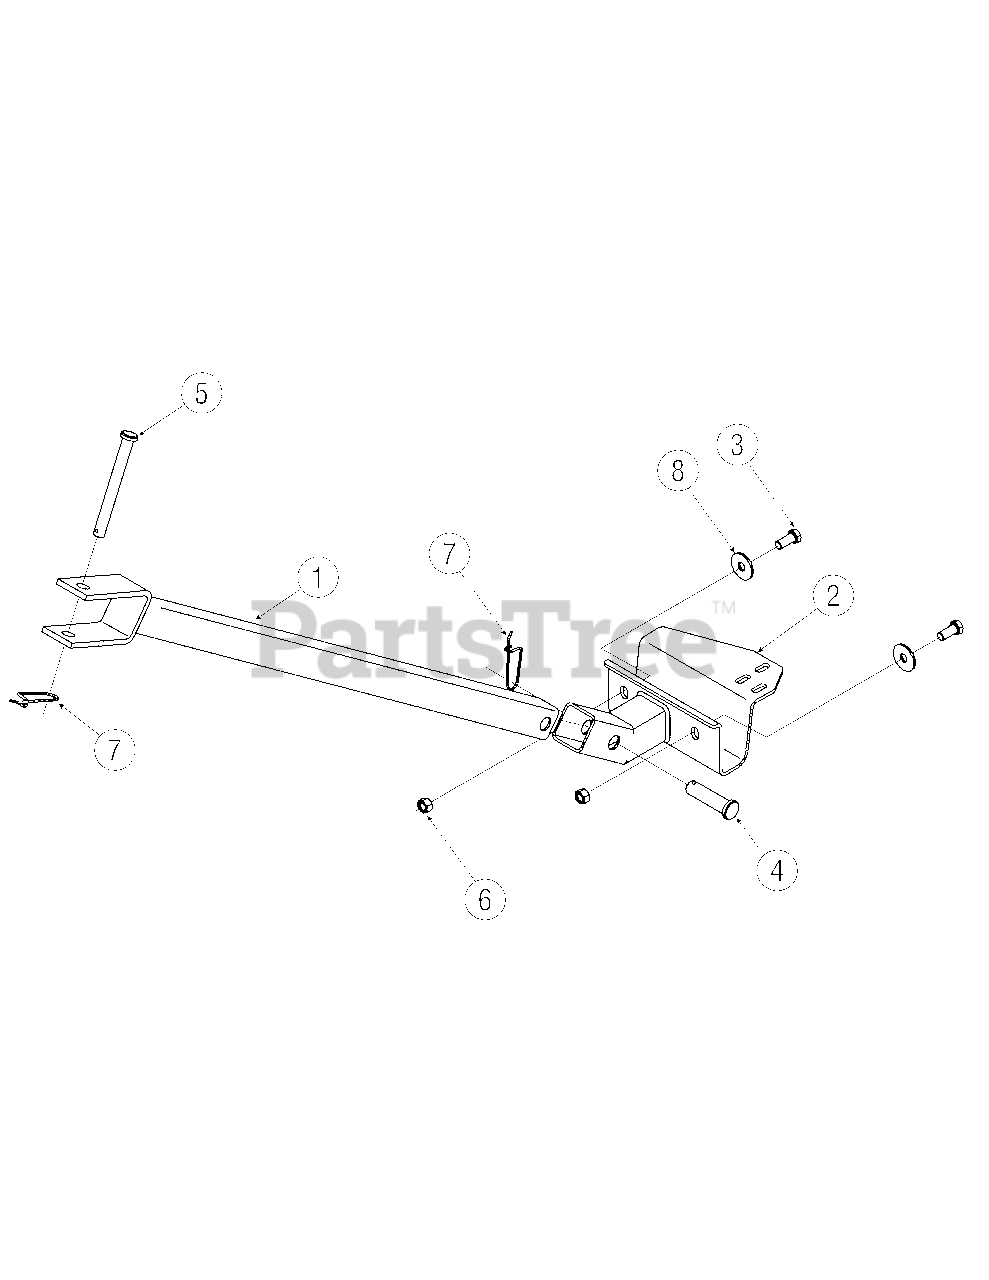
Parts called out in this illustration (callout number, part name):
3	Hex Cap Screw, 3/8-16 x.88
4	Clevis Pin,.625 x 2.4
5	Clevis Pin,.50 x 4.62
6	Flange Lock Nut, 3/8-16
7	Spring Pin
8	Flat Washer,.411 x 1.25 x 1.0
